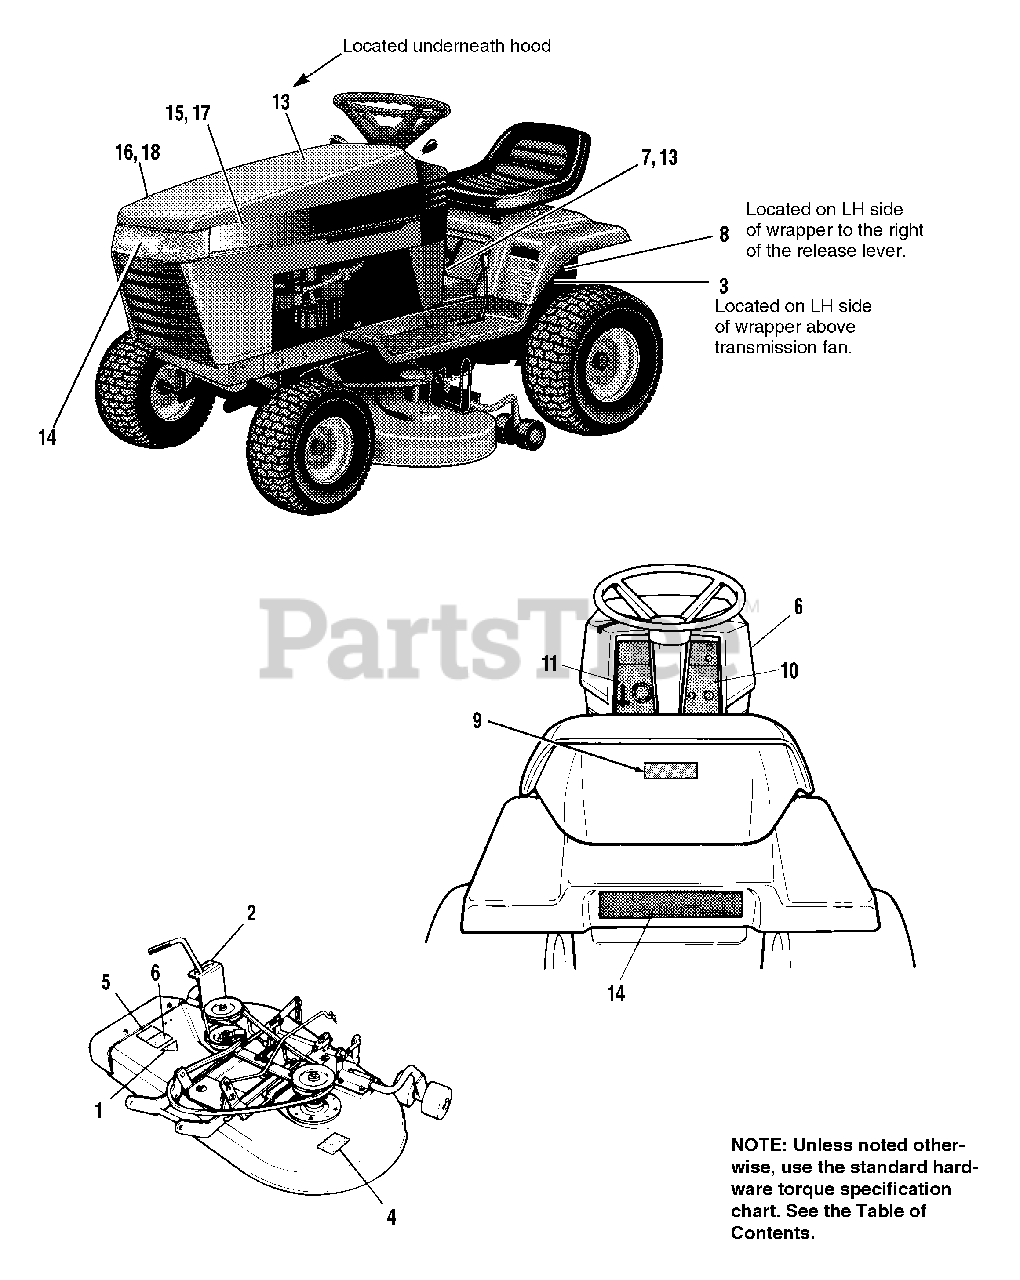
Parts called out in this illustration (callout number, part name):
1	DECAL, OPEI
2	DECAL, Mower Height
3	DECAL, Warning, Fan,
4	DECAL, Danger, Rotating Blade
5	DECAL, Danger, Deflector in Place
6	DECAL, Cutting Width, 36"
7	DECAL, Shift Pattern
8	DECAL, Release Valve,
9	DECAL, USA
10	DECAL, Dash, RH
11	DECAL, Dash, LH
13	DECAL, Drive Belt
14	DECAL, Massey Ferguson
15	DECAL, Hood, 2512G Massey Ferguson, LH
16	DECAL, Hood, 2512G Massey Ferguson, RH
17	DECAL, Hood, 2512H Massey Ferguson, LH
18	DECAL, Hood, 2512H Massey Ferguson, RH
